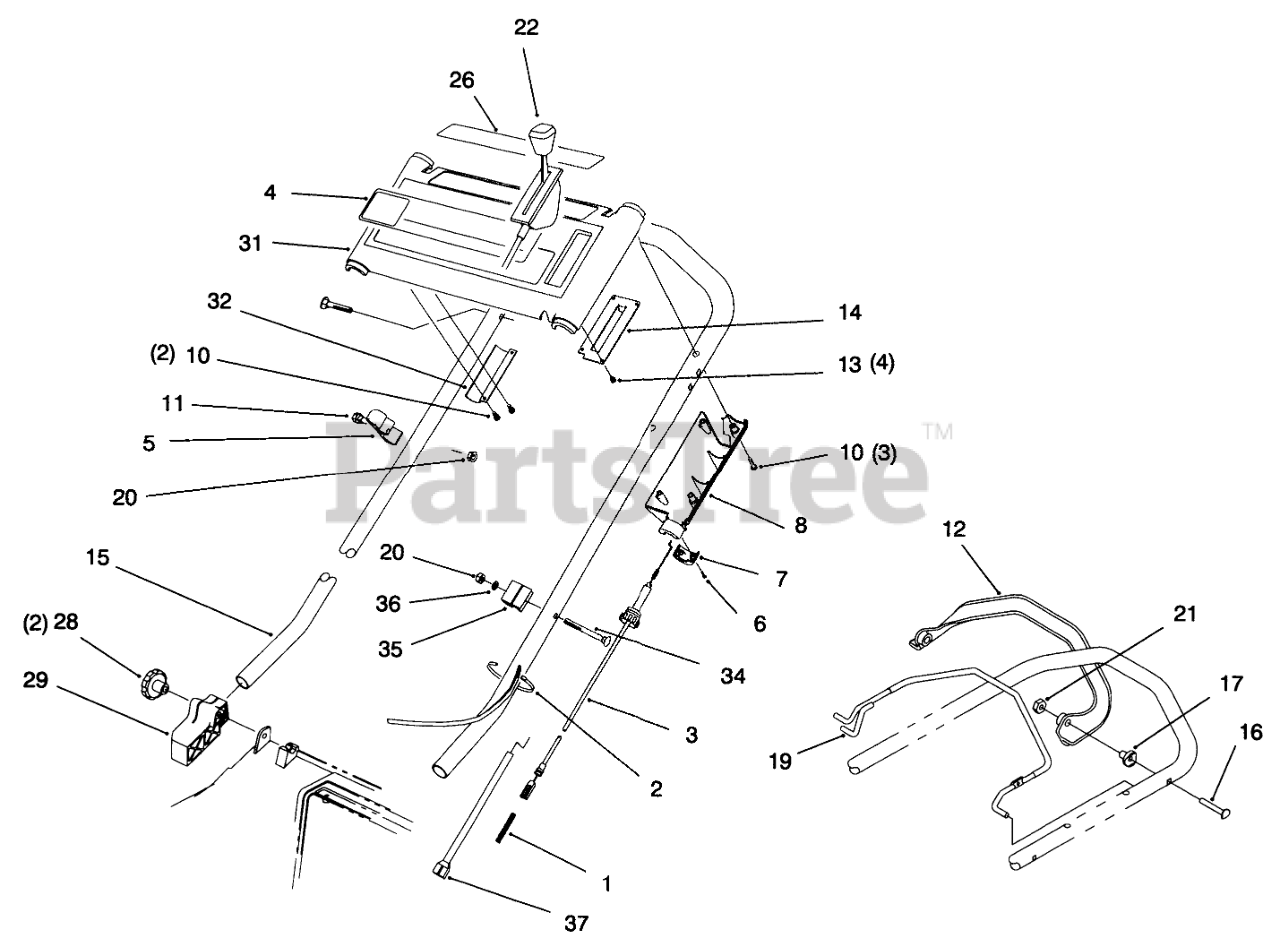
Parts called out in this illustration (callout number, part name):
1	SPRING-COMPRESSION
2	TIE-CABLE
3	ASM - TRACTION CABLE
4	DECAL - PANEL
5	GUIDE - ROPE
6	#4-14X.62 PLASTITE SCW
7	LOWER THROTTLE CAP
8	COVER-THROTTLE, LEVER
10	SCREW-PPH, PLASTITE
11	.250-20X1.625 HH SCREW
12	BAIL - TRACTION
13	#6-19X.25 PLASK FORM SC
14	THROTTLE PLATE
15	Handle
16	SCREW-HANDLE
17	SPACER-SUPPORT
19	Bail-Brake
20	NUT-LOCK, NI
21	NUT-LOCK NI
22	CONTROL - THROTTLE
26	DECAL - CONTROL PANEL
29	MOUNT-HANDLE, RH
31	Panel-Control (Incl. Ref. #4,26)
32	Bracket-Panel
34	SCREW-HANDLE
35	SUPPORT-CABLE
36	WASHER-FLAT
37	CABLE - BRAKE
